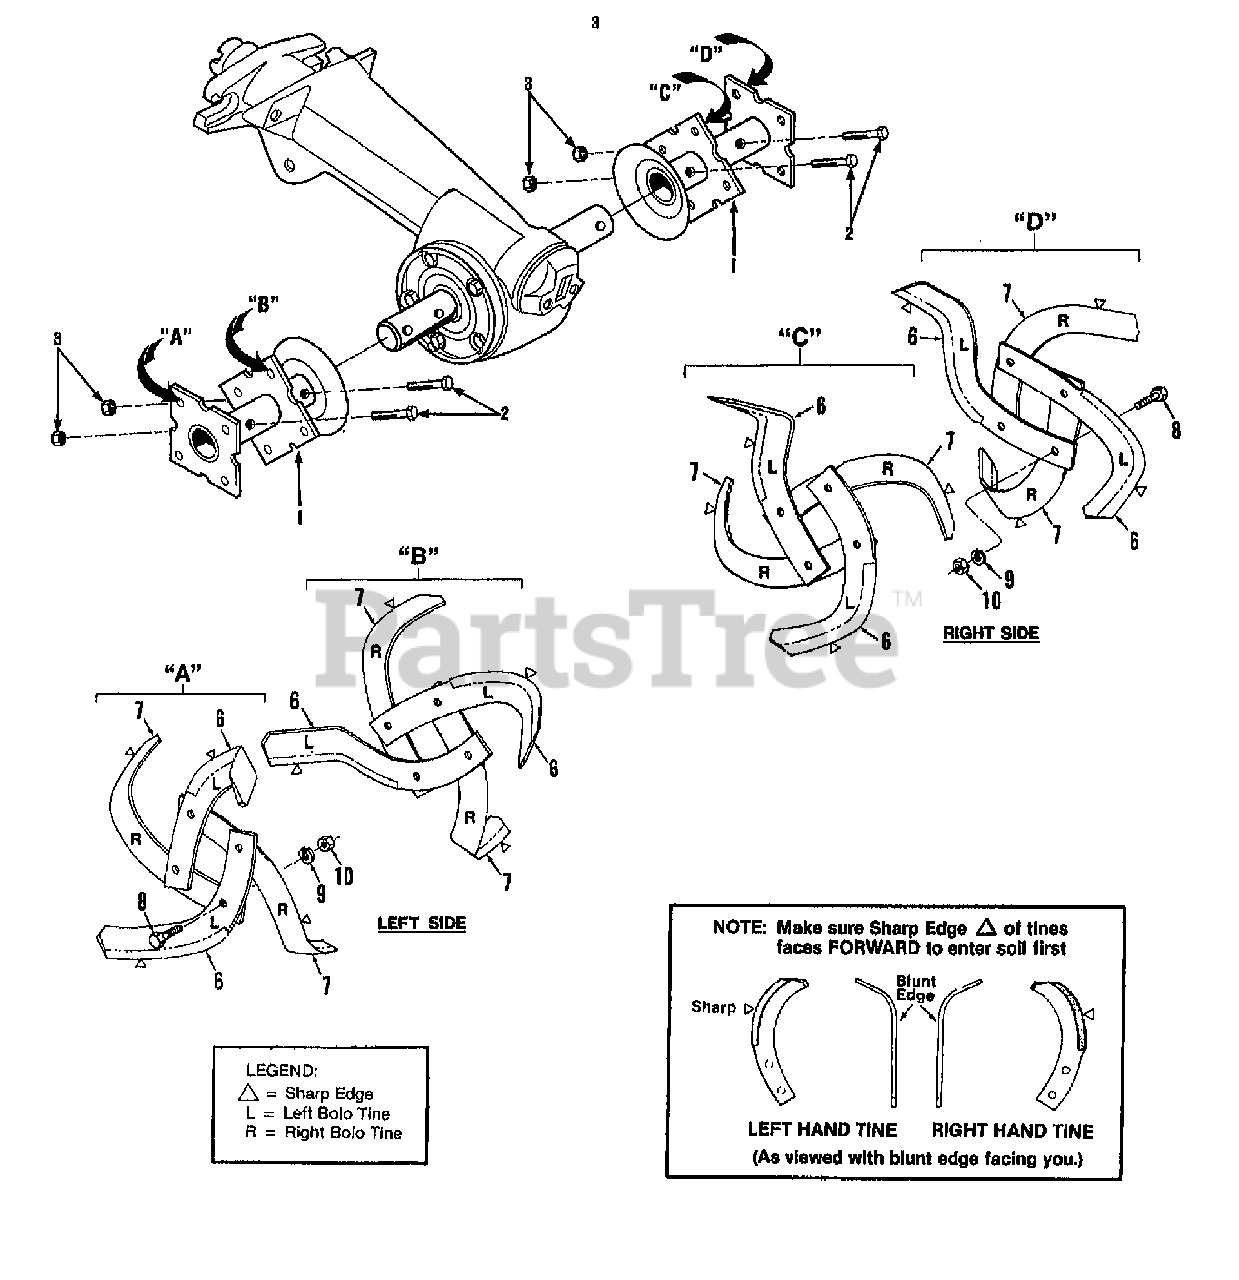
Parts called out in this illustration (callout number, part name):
1	HOLDER-TINE HORSE (RED)
2	SCR-HH 3/8-16X2.00 G8
3	NUT-H/LK 3/8-16
6	TINE-BOLO LT W/HDW(INCL. TWO EACH OF REF. NO.'S 8,9 AND 10)
7	TINE-BOLO RT W/HDW(INCL. SAME HARDWARE AS REF. NO.6)
8	SCR-HH 3/8-16X1.0 G5 ZP
9	WASHER-LK .375 @ DEPL
10	NUT-HEX 3/8-16 ZP
